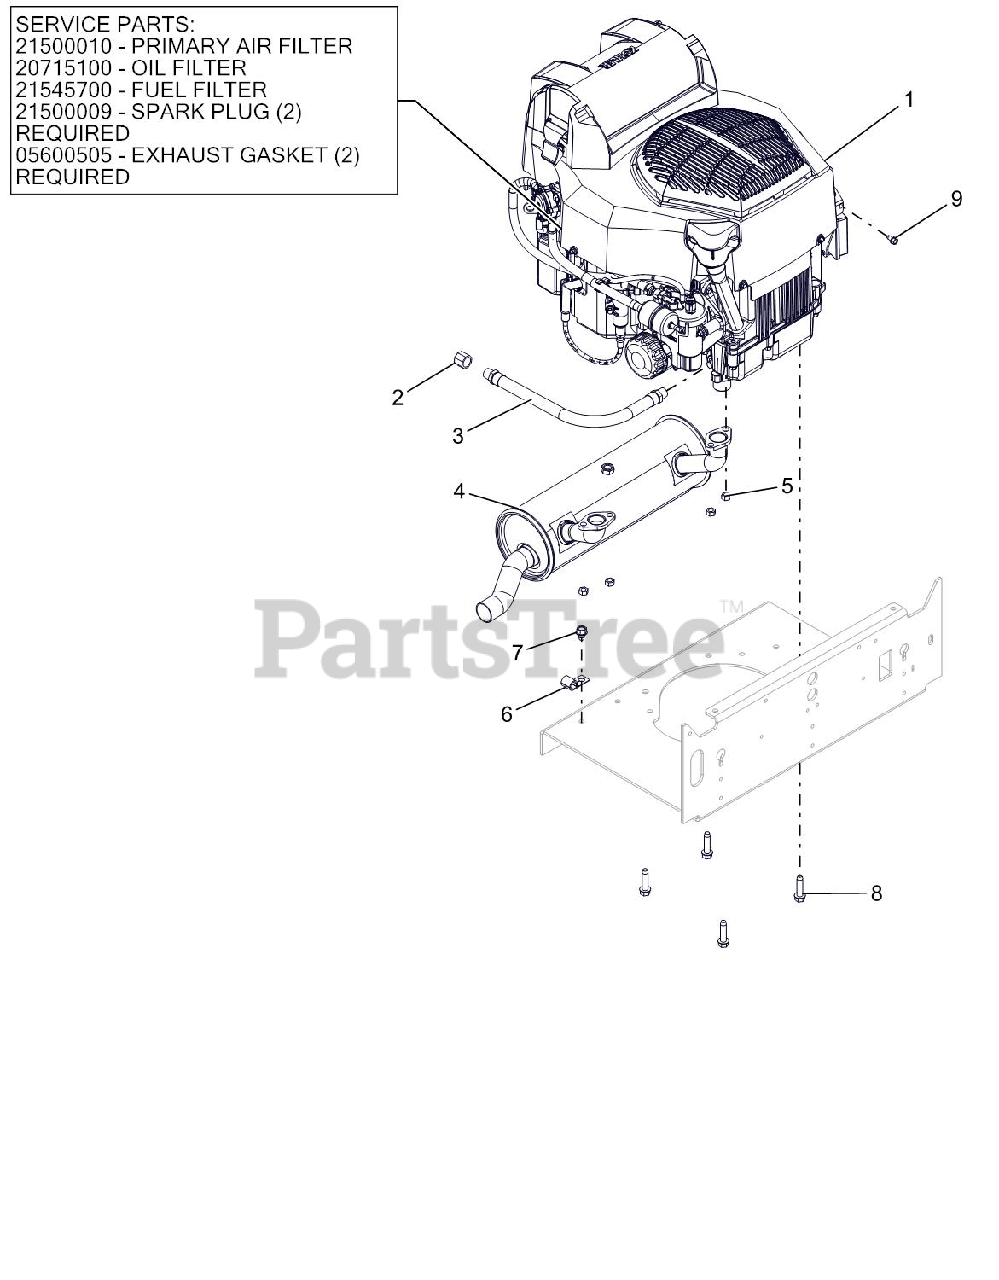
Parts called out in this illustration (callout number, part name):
1	GASKET, MUFFLER KOHLER TWIN
1	AIR CLEANER, KOHLER CONFIDANT
1	FILTER-FUEL KOHLER COURAGE PRO
1	PLUG, SPARK KOHLER
1	OIL FILTER KOHLER
1	ENGINE, KOHLER EZT740 EFI
2	PIPE CAP 3/8 NPT FEMALE
3	HOSE,HYD .38-14-0K M6N0-M6N0
4	MUFFLER, ZT725/740 EFI
5	NUT-LK-TOP M8-1.25 YWZC
7	@SCR-TAP .38-16X.50 HWH TR YWZ
8	@SCR-TAP .38-16X1.50 HWH TR YZ
9	SCR-TAP .25-20X.50 HWH TR YWZ
